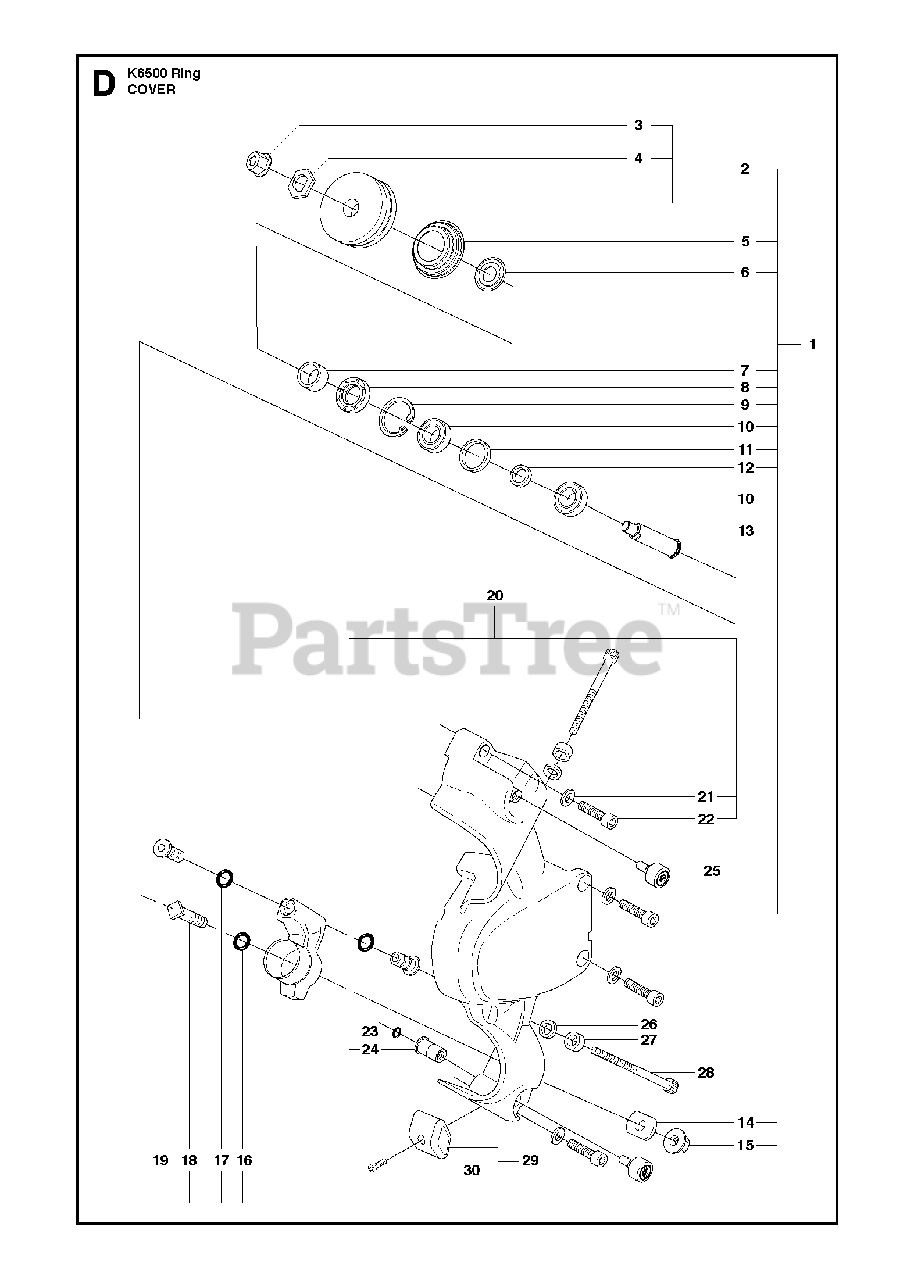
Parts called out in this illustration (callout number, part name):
3	NUTFine thread
10	BALL BEARING
28	SCREW ITXSCM
